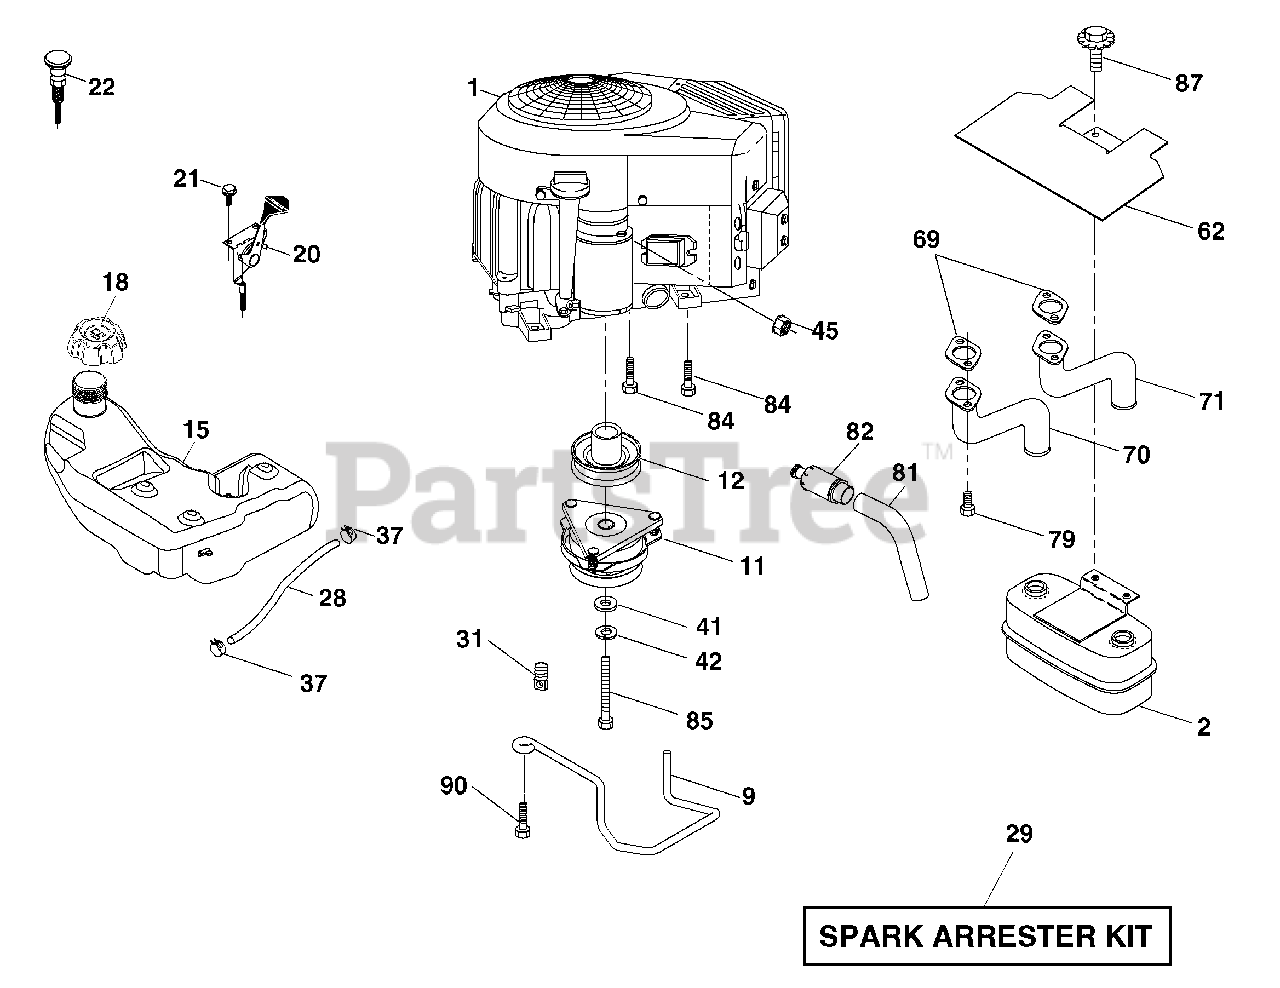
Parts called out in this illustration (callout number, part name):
9	Keeper Belt Engine
11	Clutch Ogura
12	Pulley Engine
15	Tank Fuel
18	Cap Asm
20	Control Throttle
21	Screw 10 x 3/4 Single Lead-Hex
22	Control Choke
28	Fuel Line
29	Spark Arrester Kit
31	Clip Push-In Hinged
37	Clamp Hose
41	Washer 1-1/2 OD x 15/32 ID x .250
42	Washer Lock 7/16
45	Nut Keps Hex 1/4-20 unc
62	Shield Heat Muffler
70	Exhaust Tube LH
71	Exhaust Tube RH
79	Screw Socket Head 5/16-18 x 1
81	Tube Drain Oil Easy
82	Plug Drain Oil
83	Bolt 5/16-18 unc x 1 w/Sems
84	Screw 3/8-16 x 1-1/4
85	Bolt Hex 7/16-20 x 4 x Gr. 5-1.5 Thr
87	Bolt 5/16-18 UNC x 3/4 w/Sems
90	Screw 3/8-16 x 1
